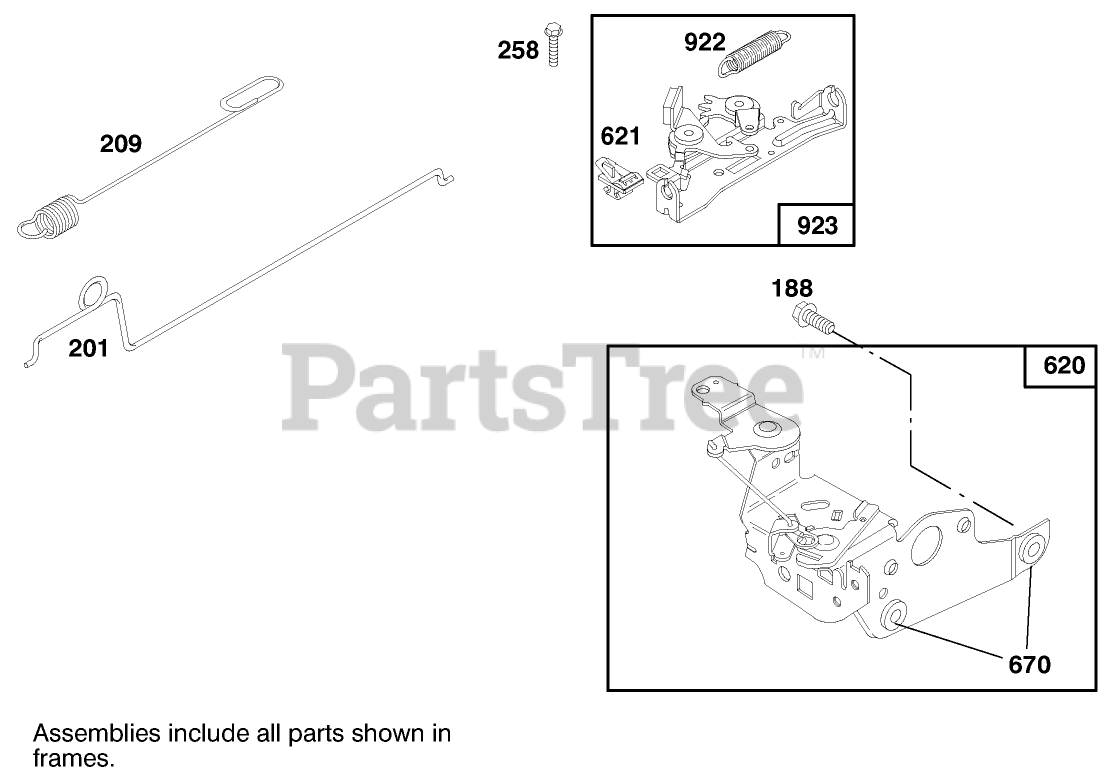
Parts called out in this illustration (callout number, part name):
188	Screw-Hex.
201	Link-Govemor
209	Governor Spring
258	Screw-Sem
620	Bracket-Control
621	Switch
670	Spacer
922	Brake Spring
923	Brake
